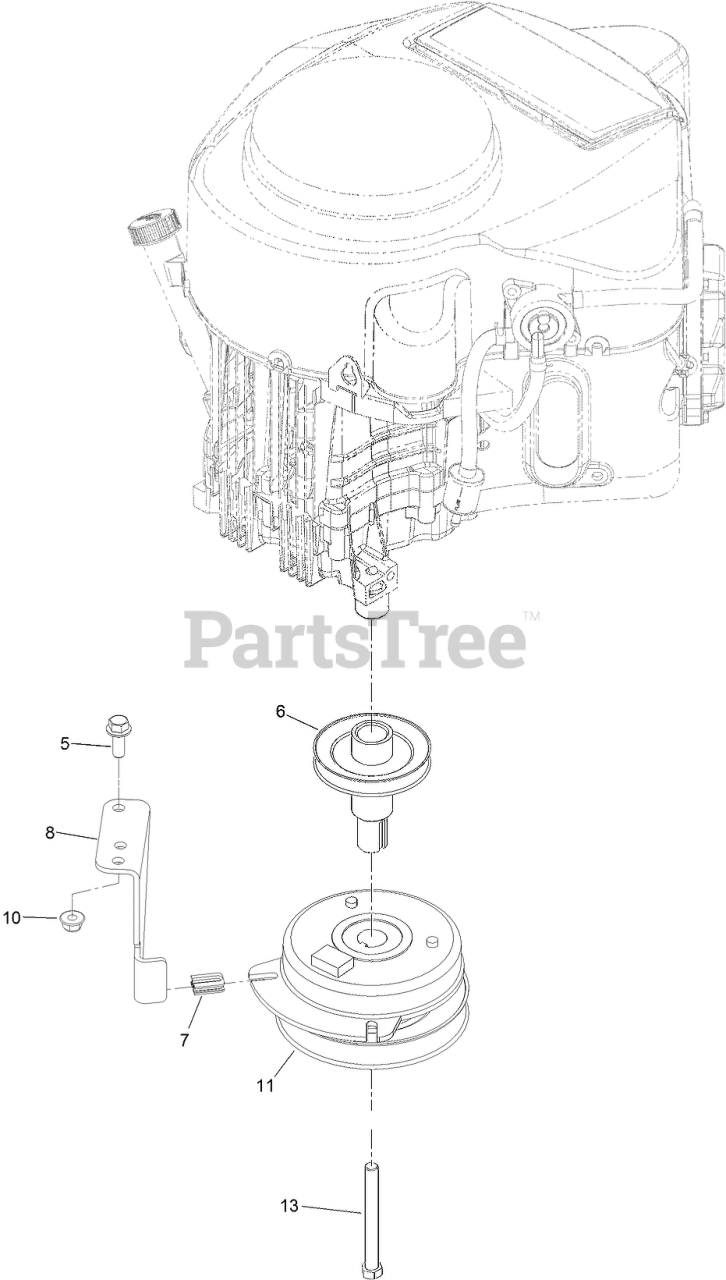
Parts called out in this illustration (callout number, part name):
5	SCREW-HHF
6	PULLEY-ENGINE
7	ISOLATOR-CLUTCH
8	STOP-CLUTCH
10	NUT-HF, NI
11	CLUTCH-PTO
13	Screw-HH
